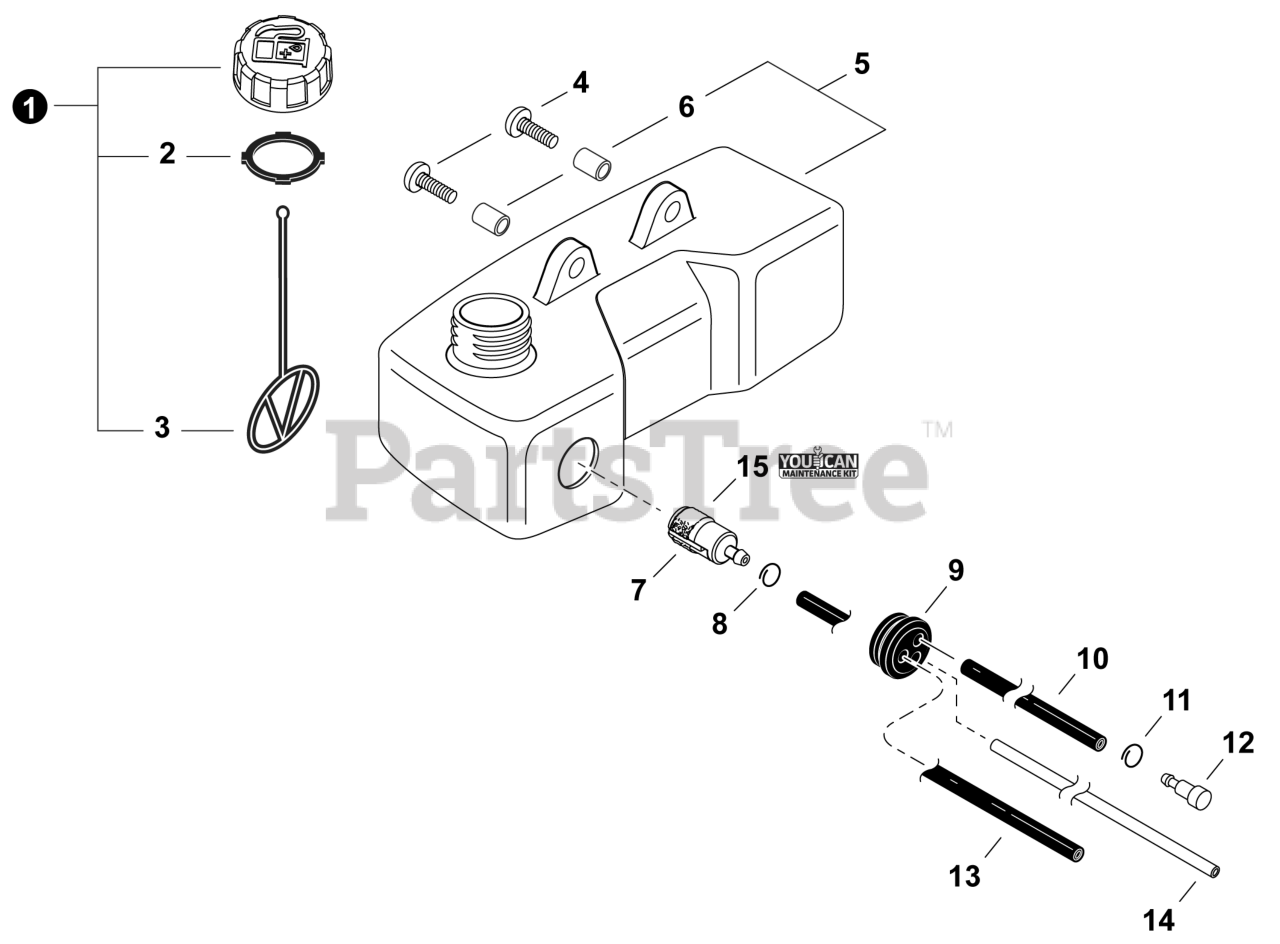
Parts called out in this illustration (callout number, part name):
1	CAP ASSY, FUEL
2	GASKET, FUEL CAP
3	CONNECTOR, CAP L= 100 MM
4	SCREW 5x15
5	TANK ASSY, FUEL
6	SPACER 6.2x7.8x6
7	FILTER, FUEL
8	CLIP 6 MM
9	GROMMET, FUEL 5
10	PIPE, FUEL 3x5x70 BLACK
11	CLIP 5.5
12	VENT ASSY
13	PIPE, FUEL 3x5x210 BLACK
14	PIPE, FUEL 3x6x50 YELLOW
15	TUNE-UP KIT - YOUCANT
